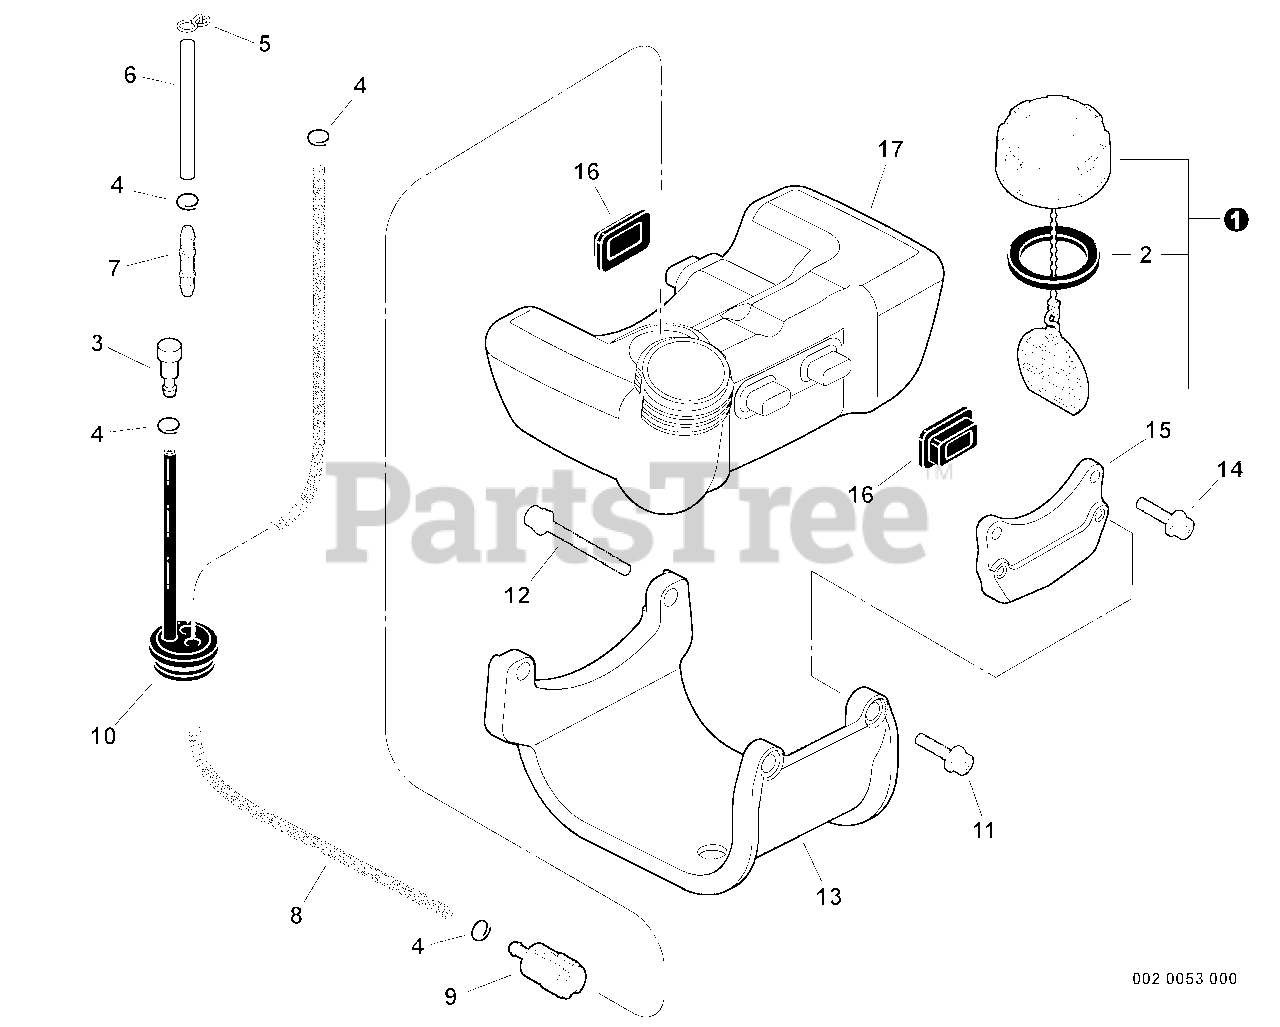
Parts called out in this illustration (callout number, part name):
1	CAP ASSY
2	GASKET, CAP
3	VENT, FUEL TANK
4	CLIP - 6
5	CLIP - BUTTERFLY
6	PIPE - CLEAR
7	CONNECTOR, PIPE
8	PIPE - BLACK
9	FILTER, FUEL
10	PIPE ASSY
11	SCREW - 5X20
12	SCREW - 5X40
13	GUARD, FUEL TANK
14	SCREW - 5X20
15	BRACKET
16	CUSHION, FUEL TANK
17	TANK, FUEL
